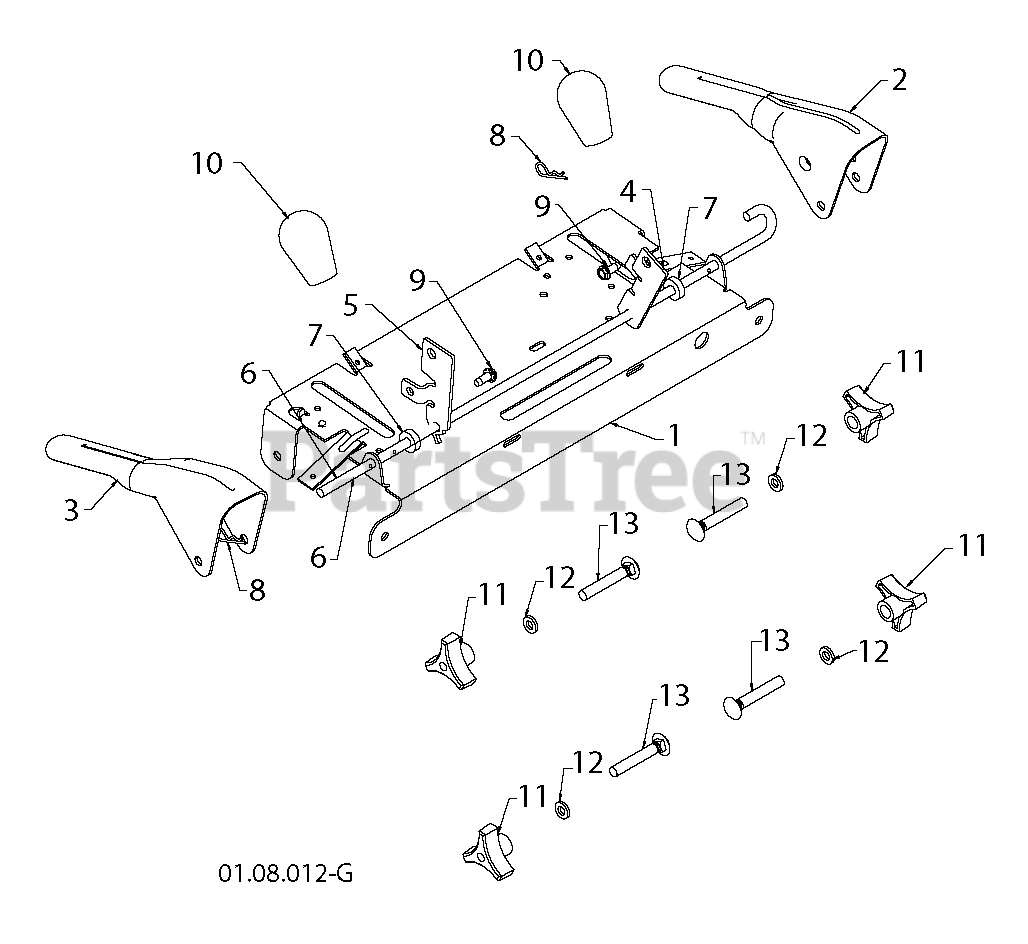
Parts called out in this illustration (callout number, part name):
1	PANEL.CONTROL.PNT.BLA
2	LEVER.CONTROL.LH.BLACK
3	LEVER.CONTROL.RH.GREY
4	ARM.TRACTION.ROD.YZ
5	ARM.IMPELLER.ROD.SNOW
6	BAIL.CONTROL.INTERLOCK
7	SPACER.CONTROL.LEVER
8	SPRING RETAINER
9	SCREW 14-20 X 5/8
10	KNOB.OVERMOLD.DS.HUSQVARNA/BLK
11	KNOB.HANDLE.3/8.TRI-POINT.BLAC
12	WASHER
13	BOLT 3/8-16 X 2-1/4
